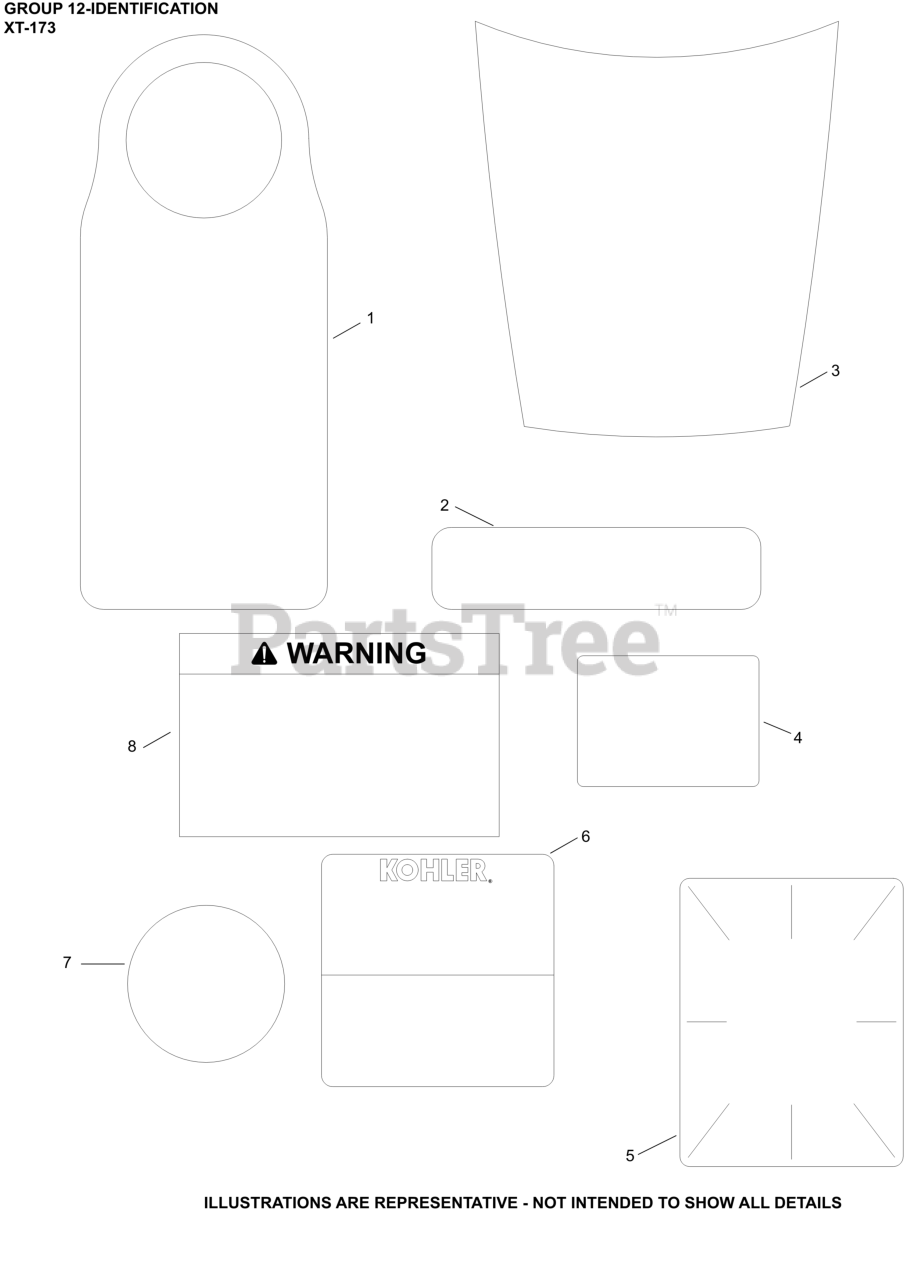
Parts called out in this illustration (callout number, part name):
1	TAG, HANG OIL WARNING
3	DECAL, NAME (XT-7)
4	DECAL, PRIMER
6	NAMEPLATE, SERVICE
8	DECAL, WARNING
